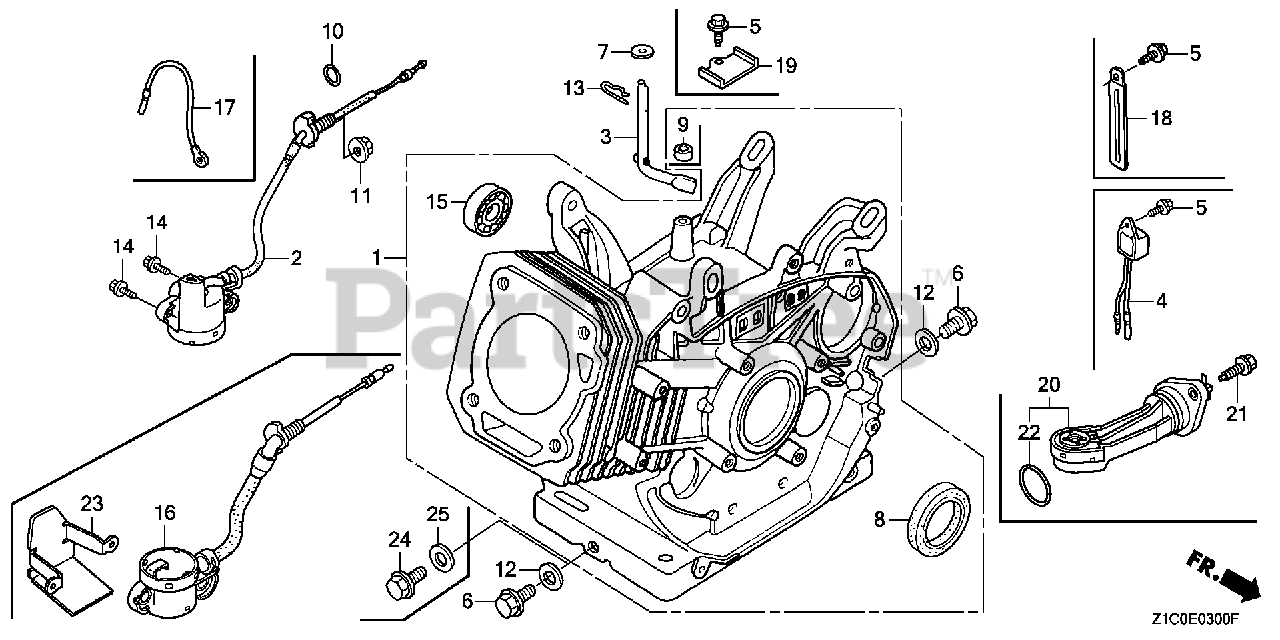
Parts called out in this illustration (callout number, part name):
1	CYLINDER ASSY. (ALERT)
2	SWITCH ASSY., OIL LEVEL
3	SHAFT, GOVERNOR ARM
4	ALERT UNIT, OIL
5	BOLT, FLANGE (6X12) (CT200)
6	BOLT, DRAIN PLUG
7	WASHER (8.2X17X0.8)
8	OIL SEAL (35X52X8) (NOK)
9	OIL SEAL (8X14X5)
10	O-RING (14MM) (ARAI) Use up to Engine SN 2949254.
10	O-RING (14MM) (NOK)
11	NUT, FLANGE (10MM)
12	WASHER, DRAIN PLUG (12MM)
13	PIN, LOCK (10MM)
14	BOLT, FLANGE (6X12) Use up to Engine SN 1543277.
15	BEARING, RADIAL BALL (6202)
